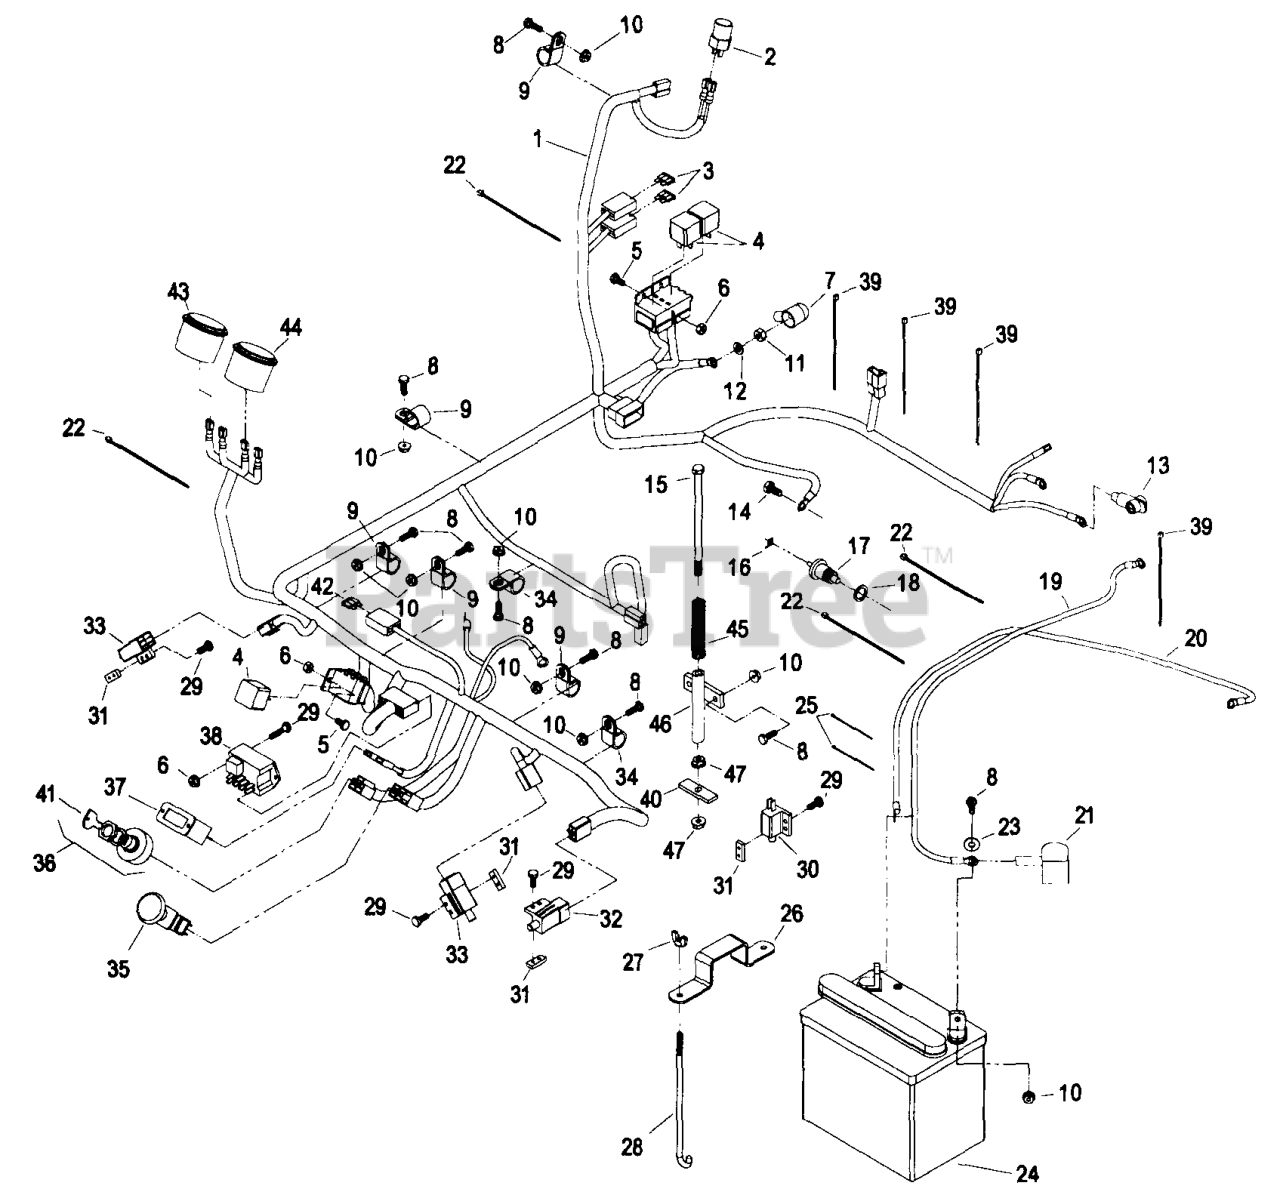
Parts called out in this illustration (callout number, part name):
2	SWITCH-THERMAL, FAN
3	FUSE-BLADE TYPE, 30 AMP
7	INSULATOR-SOLENOID
9	CLIP-LOOM
12	WASHER-LOCK
13	CAP-INSULATOR, RED
14	Screw, Hex M8-1.25 X 16
15	SCREW-HH
17	SENDER UNIT-TEMPERATURE
18	WASHER-ALUMINUM
20	WIRE-GROUND
22	TIE-PLASTIC
24	Battery-12v
25	TIE-CABLE
26	STRAP-HOLDDOWN
27	WINGNUT
28	BOLT-HOLDDOWN
30	SWITCH-CLOSED, NORMALLY
31	PLATE-TAPPED
32	SWITCH-BRAKE
34	CLIP-LOOM
36	SWITCH,IGNITION
37	METER-HOUR
38	MODULE,IGNITION INTRLOCK
39	TIE-PLASTIC
40	PLATE-SWITCH, SEAT
41	KEYS-IGNITION (SPARE PAIR
42	FUSE-BLADE TYPE, 20 AMP
43	GAUGE-VOLTMETER
44	GAUGE-TEMPERATURE
45	SPRING-SWITCH, SEAT
46	MOUNT-SPRING, SEAT
